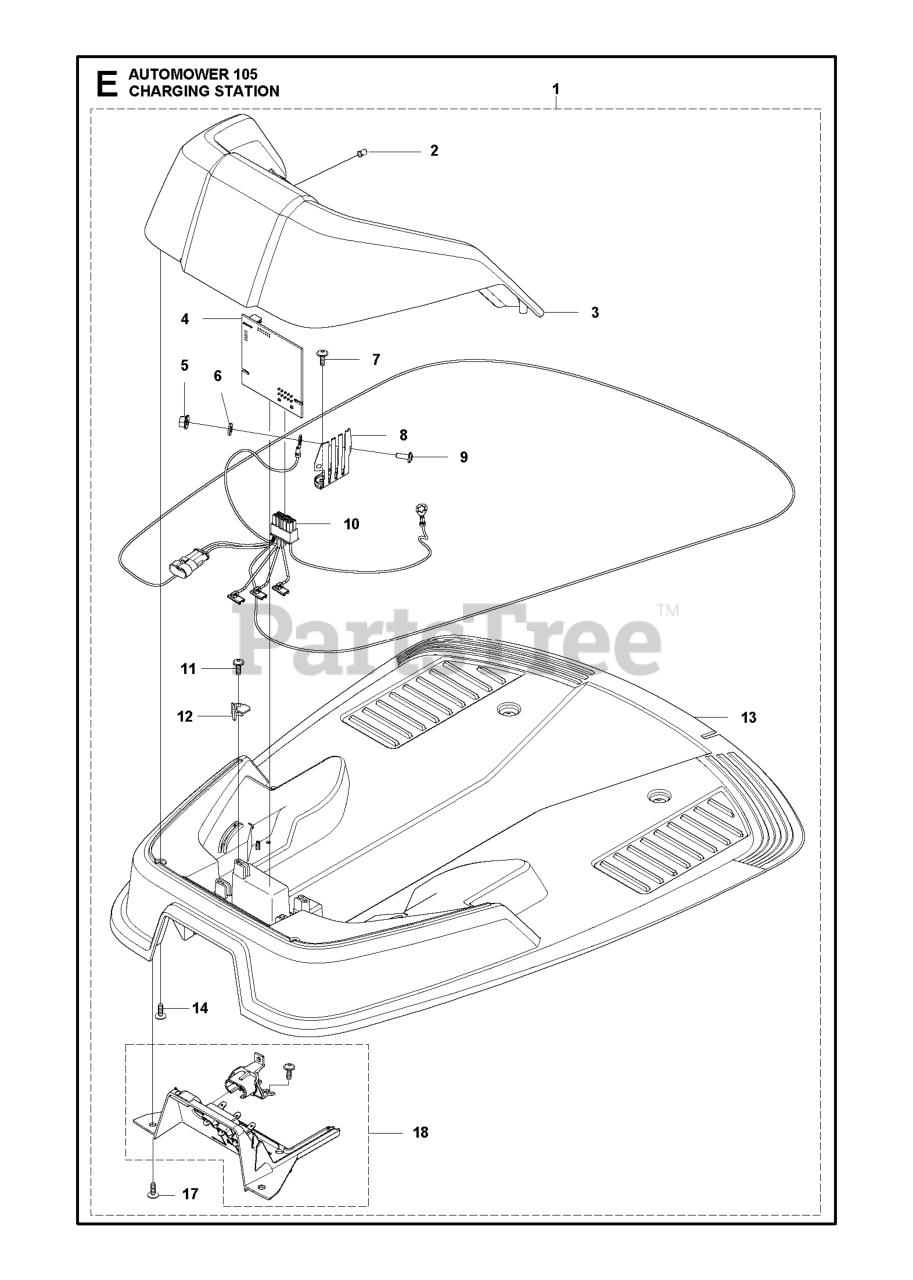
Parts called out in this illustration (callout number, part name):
2	LENS
4	PRINTED CIRCUIT ASSY P1 CS PCB
5	HEXAGON NUT FLANGE M4 A2-70
6	FIBER WASHER
7	SCREW 14MM
8	CONTACT CHARGER STATION CONTAC
9	SCREW ITXPANM M4X12 A2-70 PAT
10	CABLE ASSY CHARGING STATION
11	SCREW 14MM
12	BRACKET
13	CHARGING STATION BASE PLATE
14	SCREW 14MM
17	SCREW 14MM
18	PANEL ASSY AMP
